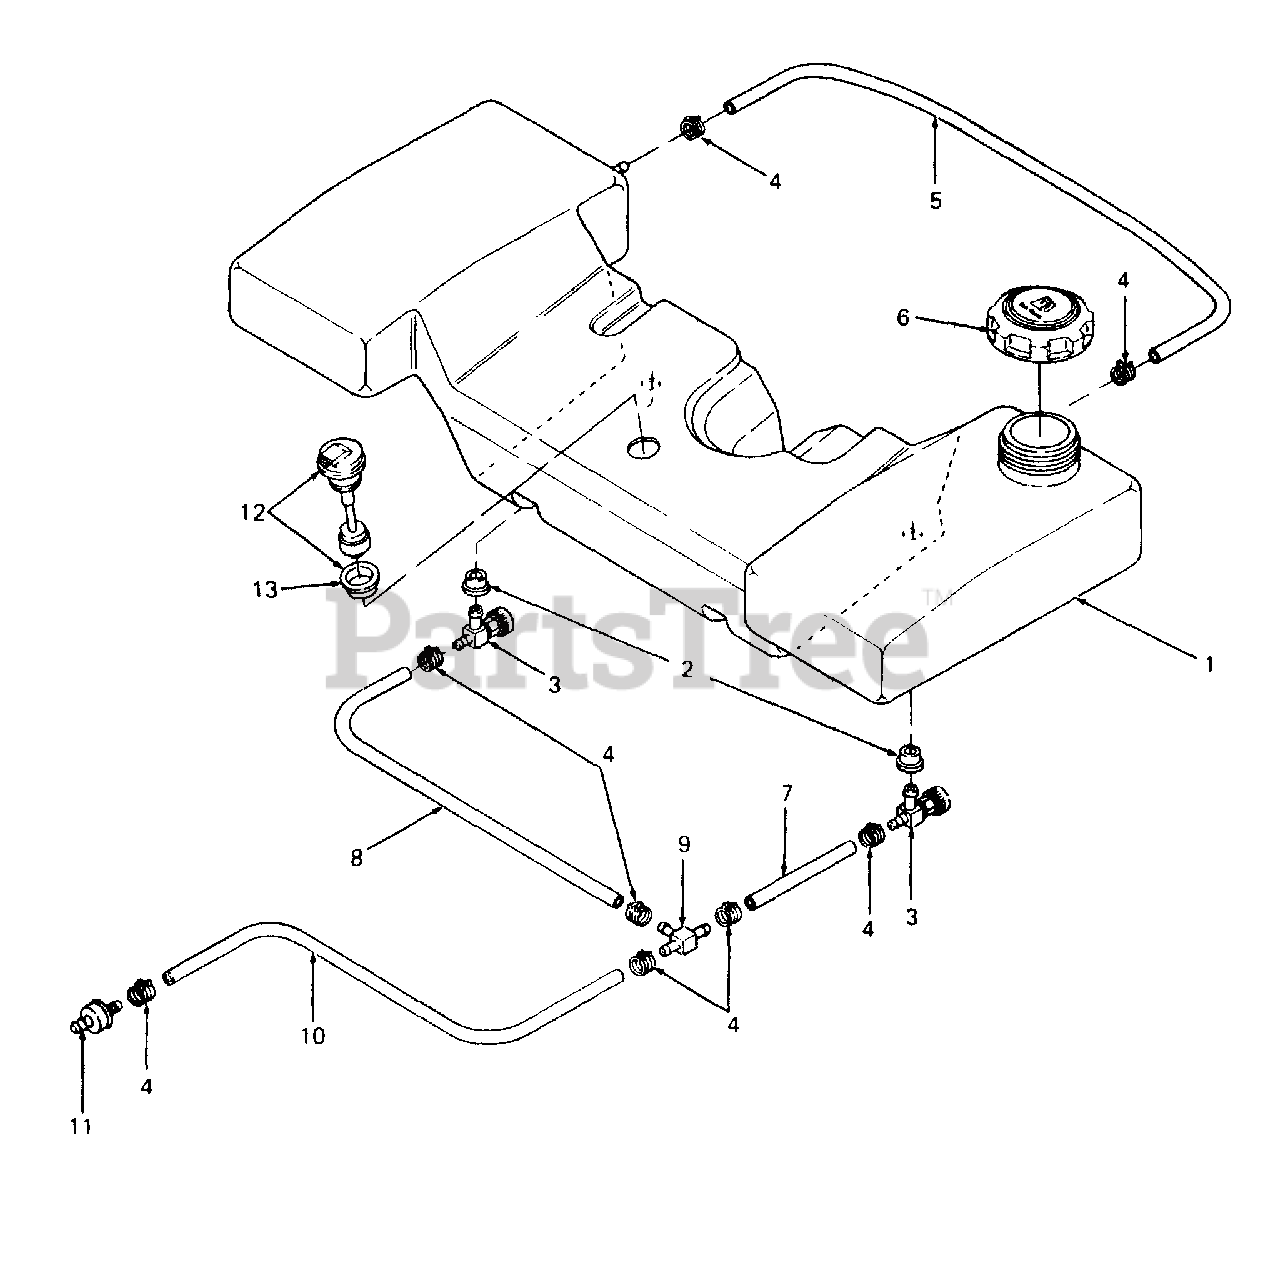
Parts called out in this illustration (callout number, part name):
1	Tank, Fuel
2	Bushing
3	Valve, Fuel Shutoff
4	Clamp, Hose
5	Line, Fuel - 24" Lg
6	Cap, Fuel
7	Line, Fuel - 5" Lg
8	Line, Fuel - 17" Lg
9	T-Fitting
10	Line, Fuel - 41" Lg
11	Filter, Fuel
12	Sensor, Low Fuel
13	Bushing, Rubber
